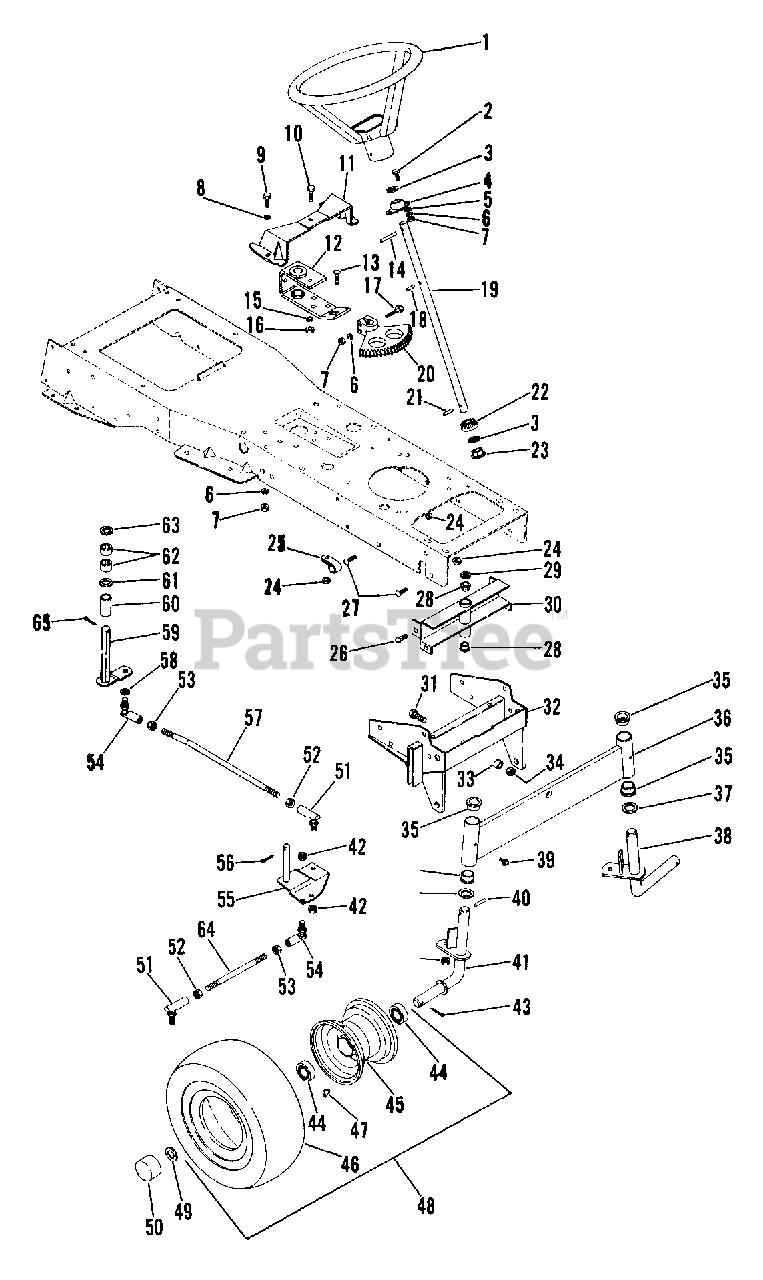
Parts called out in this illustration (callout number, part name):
1	STEERING WHEEL ASSEMBLY
1	LOGO-STEERING WHEEL
1	STEERING WHEEL CAP
2	BLT-HEX .31-18X.75 PL GR2
3	WSHR-FL-STL .754X1.125X.062 PL
4	BRG-FLG .751X2 HOLESX.81
5	WSHR-FL-STL.312X.734X.065PL
6	WSHR-LK .312X.097 PL HVY
7	NUT-HEX .312-18
8	WSHR-FL-STL .323X.625X.062 PL
9	BLT-HEX .31-18X1.00 PL GR 2
10	BLT-HEX .38-16X1.00 PL
11	STEERING SUPPORT BRACE
12	STEERING BRACKET
13	BLT-RDHDSQNK .38-16X1.0 PL
14	PIN-ROLL .250X2.00
15	WSHR-LK .375X.115 HVY PL
16	NUT-HEX .375-16
17	BLT-HEX .31-18X1.75 PL GR2
18	PIN-ROLL .188X1.00
19	STEERING COLUMN
20	STEERING BEVEL GEAR
21	PIN .249X1.125 DRIV-LOK SP
22	PINION GEAR-STEERING
23	BSHG-FLG .750X1.093X.625X1.375
24	NUT-LK-FLG .375-16 PL
25	BLT-HEX .25-20X.50 GR2 PL
26	BLT-RDHDSQSHNK .38-16X1.00 PL
27	BLT-RDHDSQNK .38-16X.75 SHT PL
28	BSHG-FLG .625X.750X.500X.875BR
29	WSHR-FL-STL .630X1.005X.062 PL
30	PIVOT CHANNEL
31	BLT-HEX .50-13X1.50 PL GR5
32	FRONT AXLE SUPPORT
33	SPACER .531X.748X.524
34	NUT-LK-CROWN .50-13 GR C PL
35	BSHG-FLG 1.000X1.25X.75X1.50
36	FRONT AXLE W/BUSHINGS AND ZERK
36	FRONT AXLE ASSEMBLY
37	WSHR-FL-STL 1.010X1.505X.062PL
38	LEFT SPINDLE
39	SPIN DRIVE ZERK FITTING
40	PIN-ROLL .250X1.38
41	RIGHT SPINDLE
42	NUT-LK .50-20 PL
43	PIN-COTR .25X1.50 ST PL
44	BRG-BALL 1.0X2.0X.55
47	SPIN DRIVE ZERK FITTING
48	T/WHL ASSY 15 X6-6
48	T/WHL ASSY
49	WSHR-FL-STL 1.015X1.500X.125
50	FRONT HUB CAP
51	BALL JOINT L.H.
52	NUT-JAM .50-20 LH THD PL
53	NUT-JAM .50-20 PL
54	BALL JOINT R.H.
55	STEERING PIVOT
56	PIN-COTR .12X1.0 PL
57	STEERING LINK
58	WSHR-FL-STL .531X.938X.104 PL
59	ARM & SHAFT
60	SPACER .780X.900X2.094
61	WSHR-FL-STL .880X1.250X.062
62	BSHG-SLV .750X1.000X.750 HX SB
63	WSHR-FL-STL .875X1.250X.075
63	TIE ROD
64	TIE ROD
65	PIN-COTR .18X1.25 PL
66	CONTROL SUPPORT
